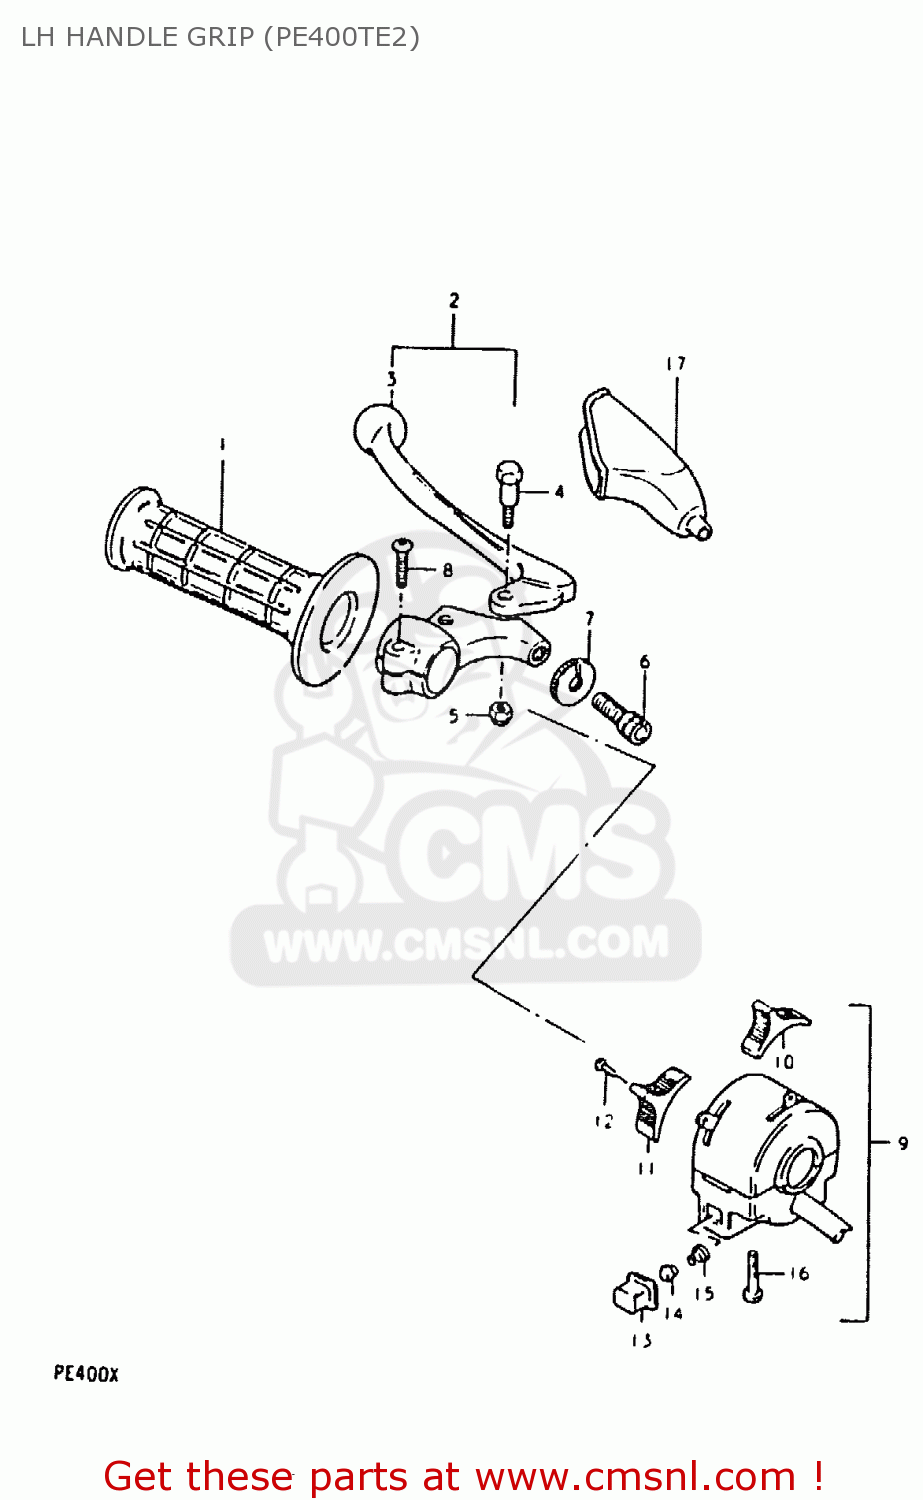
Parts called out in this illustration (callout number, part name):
1	GRIP,LEFT
2	LEVER ASSY,CLUTCH
3	LEVER,CLUTCH
4	BOLT,LEVER
5	NUT 6MM
6	ADJUSTER,CABLE
7	NUT,CABLE ADJUSTER
8	SCREW
9	SWITCH ASSY, HANDLE LH
10	KNOB,LIGHTING SWITCH
11	KNOB,DIMMER SWITCH
12	SCREW
13	BUTTON,HORN
14	CONTACT
15	SPRING
16	SCREW
17	COVER,CLUTCH LEVER
